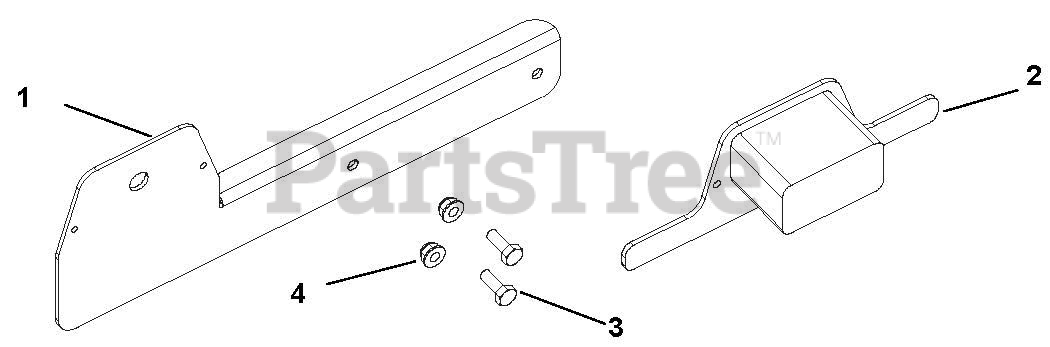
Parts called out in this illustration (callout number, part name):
1	BRKT, SPLITTER LICENSE PLATE
2	LICENSE PLATE BRACKET W/ LIGHT
3	@BLT-HEX .25-20X.75 GR5 YWZC
4	@NUT-LK-NYL-FLG .25-20 YWZC
